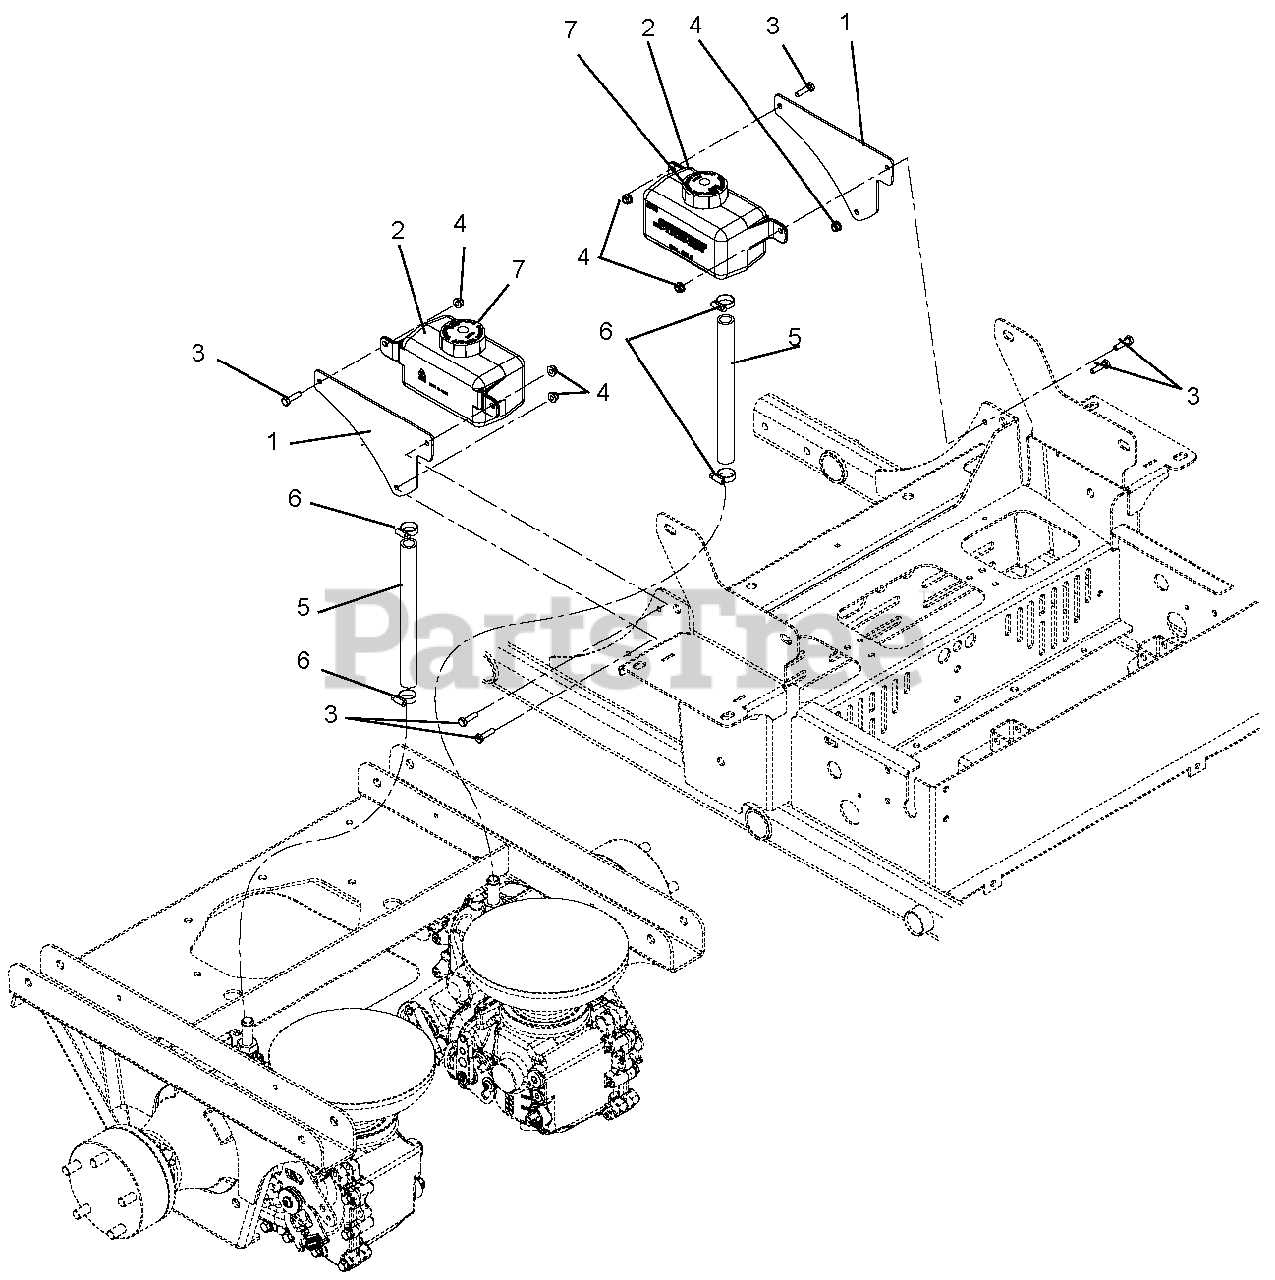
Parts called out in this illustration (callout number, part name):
1	Plate, Hydro Overflow Tank Mounting
2	Tank, Hydraulic 1000ML
3	Bolt, Hex .25-20 x 1.00 Grade 5 YWZC
4	Nut, Locking Nyloc Flange .25-20 YWZC
5	Hose, Hydro Overflow
6	Clamp, .88 Dia. Hose
7	Cap, Hydro Reservoir REPLAC.
